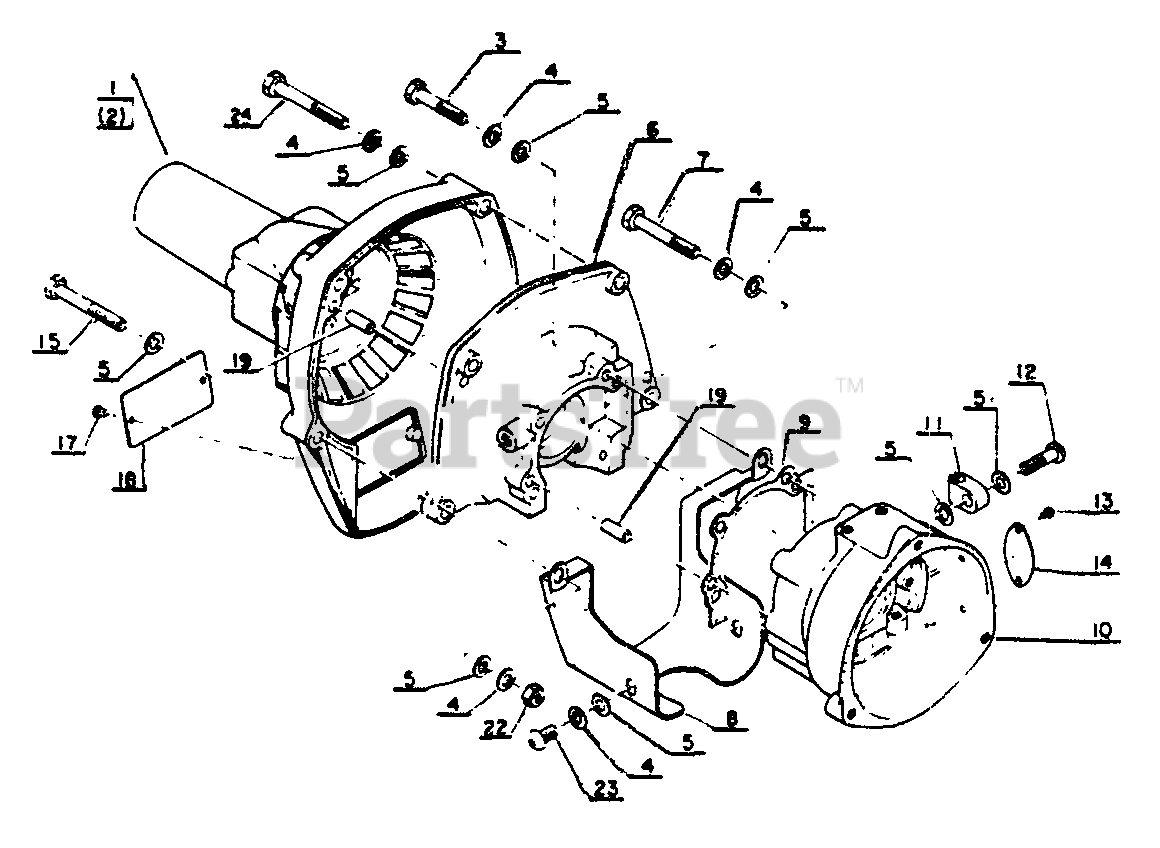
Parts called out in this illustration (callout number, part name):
1	CASE, FAN
3	BOLT, CRANKCASE (A)
4	WASHER, SPRING 5
5	WASHER, FLAT 5.5×10×0.8
6	CRANKCASE - REAR
7	BOLT, CRANKCASE (B)
8	SHIELD, CYLINDER
9	GASKET, CRANKCASE
10	CRANKCASE - FRONT
11	CLIP, HIGH TENSION CORD
12	SCREW 5×18
14	MODEL PLATE
15	BOLT 5×40
17	RIVET
18	NAME PLATE
19	PIN, DOWEL
22	NUT M5
23	SCREW 5×10
24	BOLT - 5×14
